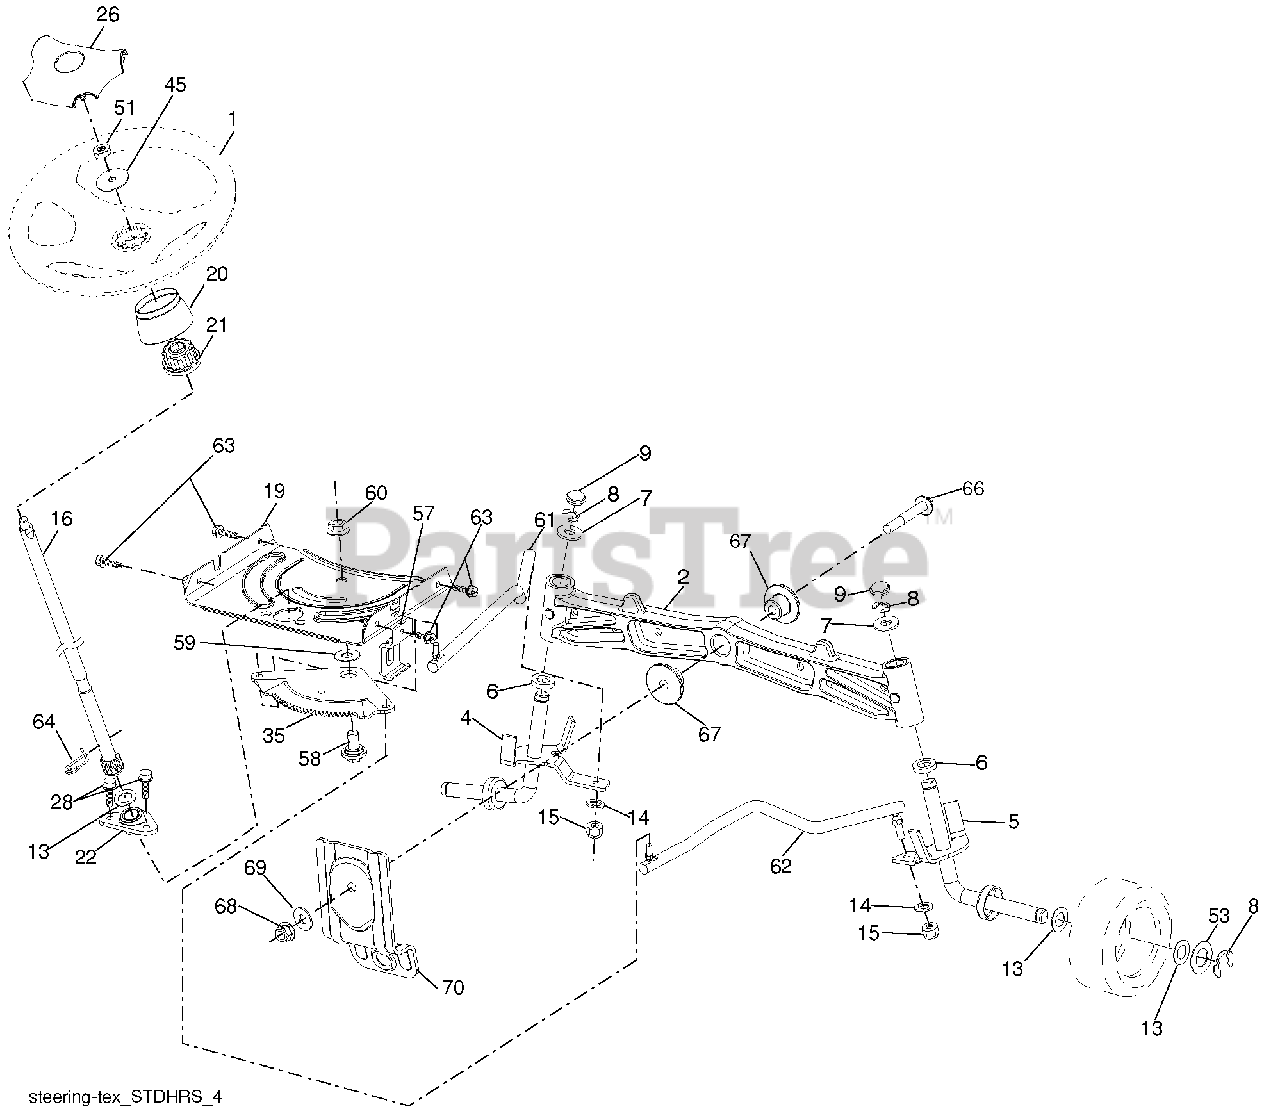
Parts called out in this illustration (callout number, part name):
1	Wheel, Steering
2	Axle Asm. Front
4	Spindle Asm. LH
5	Spindle Asm. RH
6	Washer Thrust .75 x 1.230
7	Washer 25/32 x 1-5/8 x 16 Ga.
8	Ring, Clip #T5304-75
9	Cap, Spindle
13	Washer 25/32 x 1-1/4 x 16 Ga.
14	Washer, Lock Hvy. Hlcl. Spr. 3/8
15	Nut, Crown Lock 3/8-24 unf
16	Shaft Steering
19	Plate Steering
20	Boot, Steering
21	Adapter, Wheel Steering
22	Bushing, Strg. Blk.
26	Insert, Wheel Steering
28	Screw 3/8-16 x 3/4
35	Gear, Sector Plate
45	Washer 11/32 ID x 2-3/8 OD x 12 Ga.
51	Nut Hex Jam Toplock 1/2-20 unf
53	Washer Hardened .793 x 1.637 x .060
57	Bracket Upstop
58	Bolt Shoulder Sector Pivot CFM
59	Washer Thrust Sector Steering
60	Nut Flange Lock 5/8-11
61	Draglink, LH
62	Draglink, RH
63	Screw 5/16-18 x 3/4
64	Retainer Clip Spring Steering
66	Bolt Hex Fghd. 7/16-14 x 3 Serr.
67	Bushing PM Front Axle
68	Nut Lock Flange 7/16-14 Gr. 5
69	Washer 1.5 x .505 x .118
70	Bracket Deck Susp. Front
